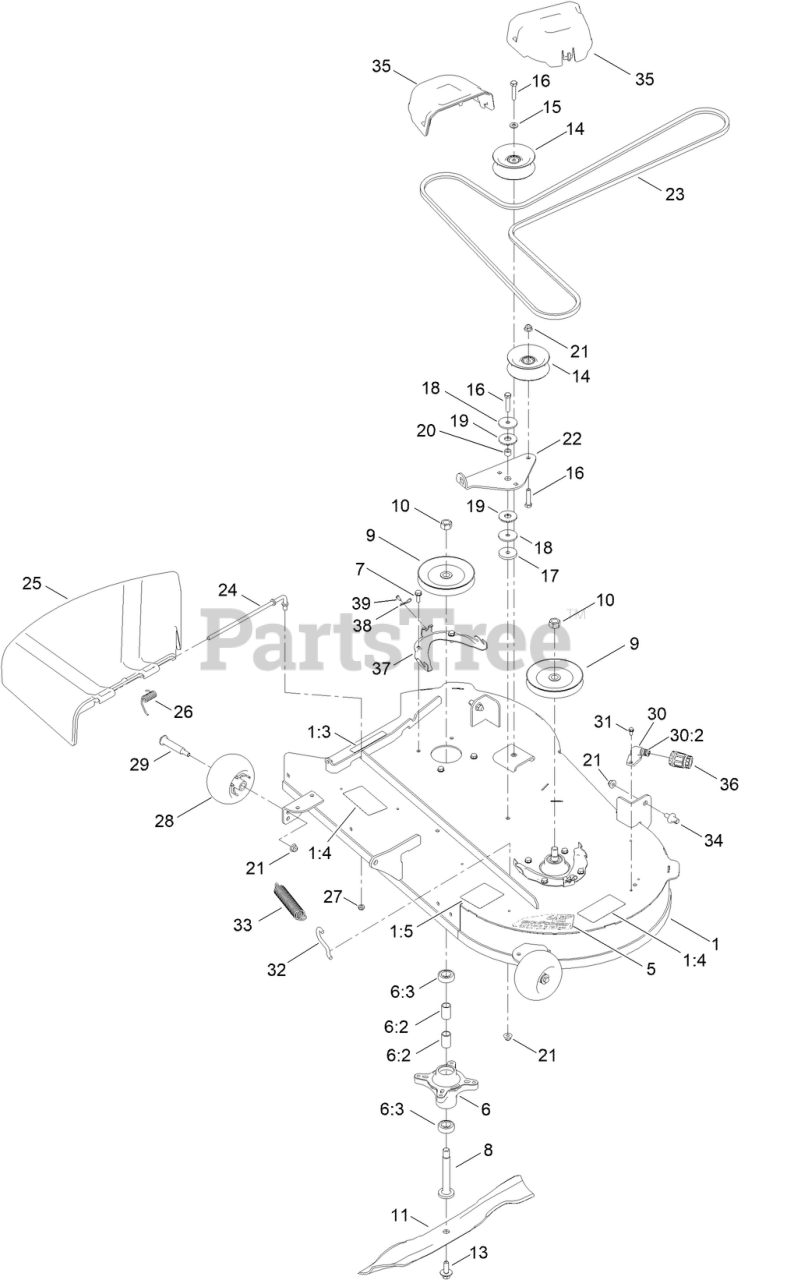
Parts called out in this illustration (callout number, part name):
1	42IN DECK AND DECAL ASM
1:3	DECAL-DANGER
1:4	DECAL-DANGER, DECK
1:5	DECAL-ROUTING, BELT
5	DECAL-DECK
6	SPINDLE ASM
6:2	SPACER
6:3	BEARING-BALL
7	SCREW-TAPTITE
8	SHAFT-SPINDLE
9	Pulley
10	NUT-HEX
11	BLADE-21.6 IN
13	BOLT-BLADE, SEMS
14	PULLEY-IDLER, FLAT
15	WASHER-FLAT
16	SCREW-HH
17	WASHER-PLAIN
18	WASHER-REBOUND
19	WASHER-FRICTION, COMPOSITE
20	SPACER
21	NUT-HF, NI
22	ARM-IDLER
23	V-BELT
24	ROD-PIVOT
25	DEFLECTOR-DISCHARGE
26	SPRING-TORSION
28	ROLLER-SCALP, ANTI
29	BOLT-SHOULDER
30	FITTING-WASHOUT
30:2	O-RING
31	SCREW-HWH
32	HOOK-RETURN SPRING
33	SPRING-EXTENSION
34	PIN-DECK
35	COVER-BELT
36	CONNECTOR-HOSE
37	BRACKET-COVER, BELT
38	PIN-HAIR
39	SCREW
